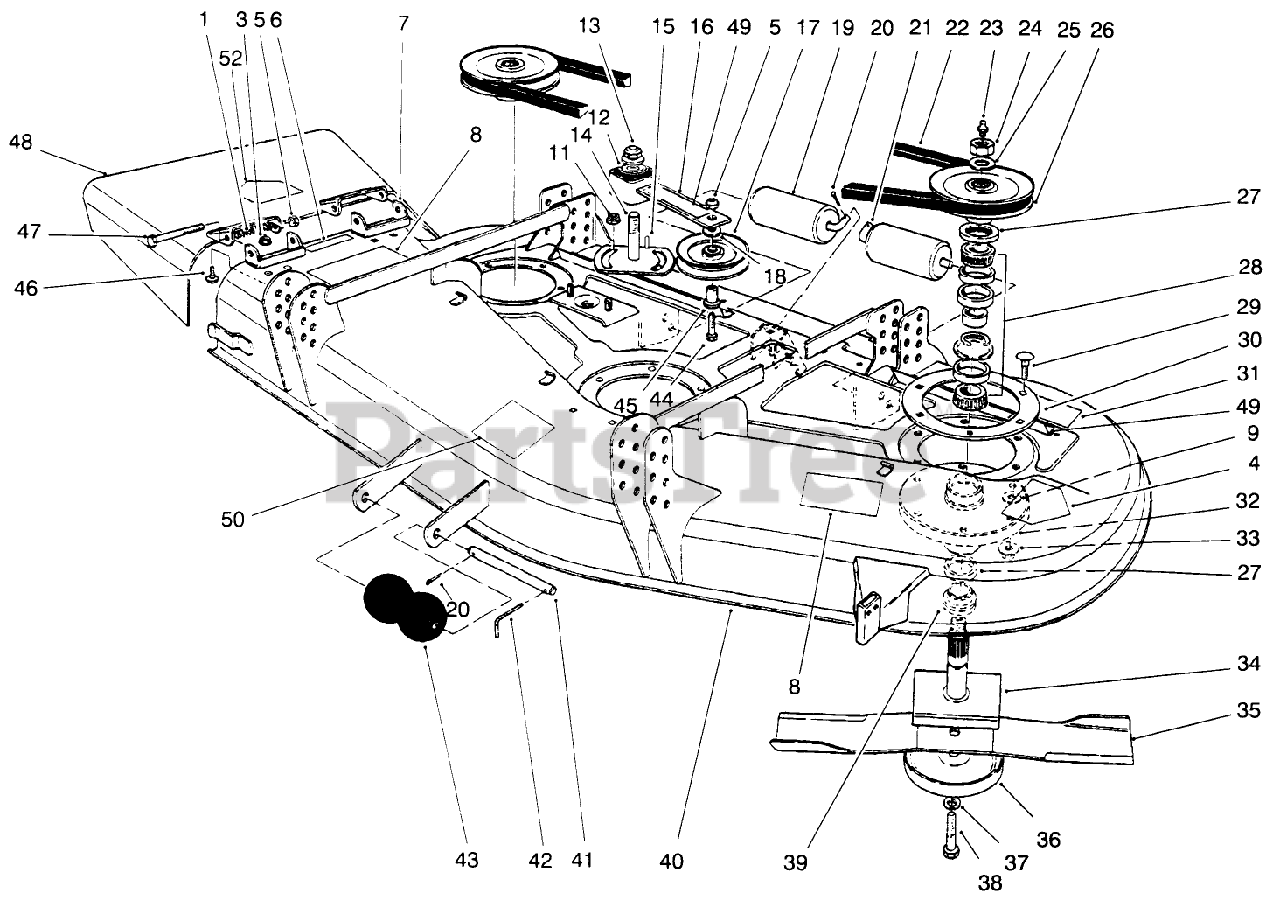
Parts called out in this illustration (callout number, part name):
1	SPRING
3	NUT-HF
4	DECAL-DANGER
5	NUT-HEX
6	DECAL-DANGER
7	Bracket-Pivot
8	DECAL-DANGER, THROWN OBJECT
9	WASHER-FLAT
11	NUT-HHF, WHIZ
12	WASHER-FLAT
13	NUT-LOCK, NI
14	PLATE-IDLER
15	KEY-SQUARE
16	IDLER ARM ASM
17	PULLEY-IDLER
18	WASHER-FLAT
19	ROLLER-DECK
20	PIN-COTTER
21	SHAFT-ROLLER, REAR
22	V-BELT
23	FITTING-GREASE
24	NUT-HEX
25	WASHER
26	PULLEY AND HUB ASM
27	SEAL-OIL
28	BEARING ASM
29	SCREW-CARR
30	SUPPORT-DECK, RING
31	DECAL-TORQUE
32	HOUSING-SPINDLE
33	NUT-HF
34	SHAFT
35	Blade
36	CUP-SCALP, ANTI
38	BOLT-BLADE
39	SPACER
40	Cutting Deck
41	SHAFT-ROLLER
42	PIN-SPECIAL
43	ROLLER
44	SCREW-HH
45	BUSHING-PULLEY
46	SCREW-CARR
47	SCREW-HH
48	Deflector-Grass (Incl. Ref. #52)
49	DECAL-DANGER
50	DECAL
52	DECAL-DANGER
